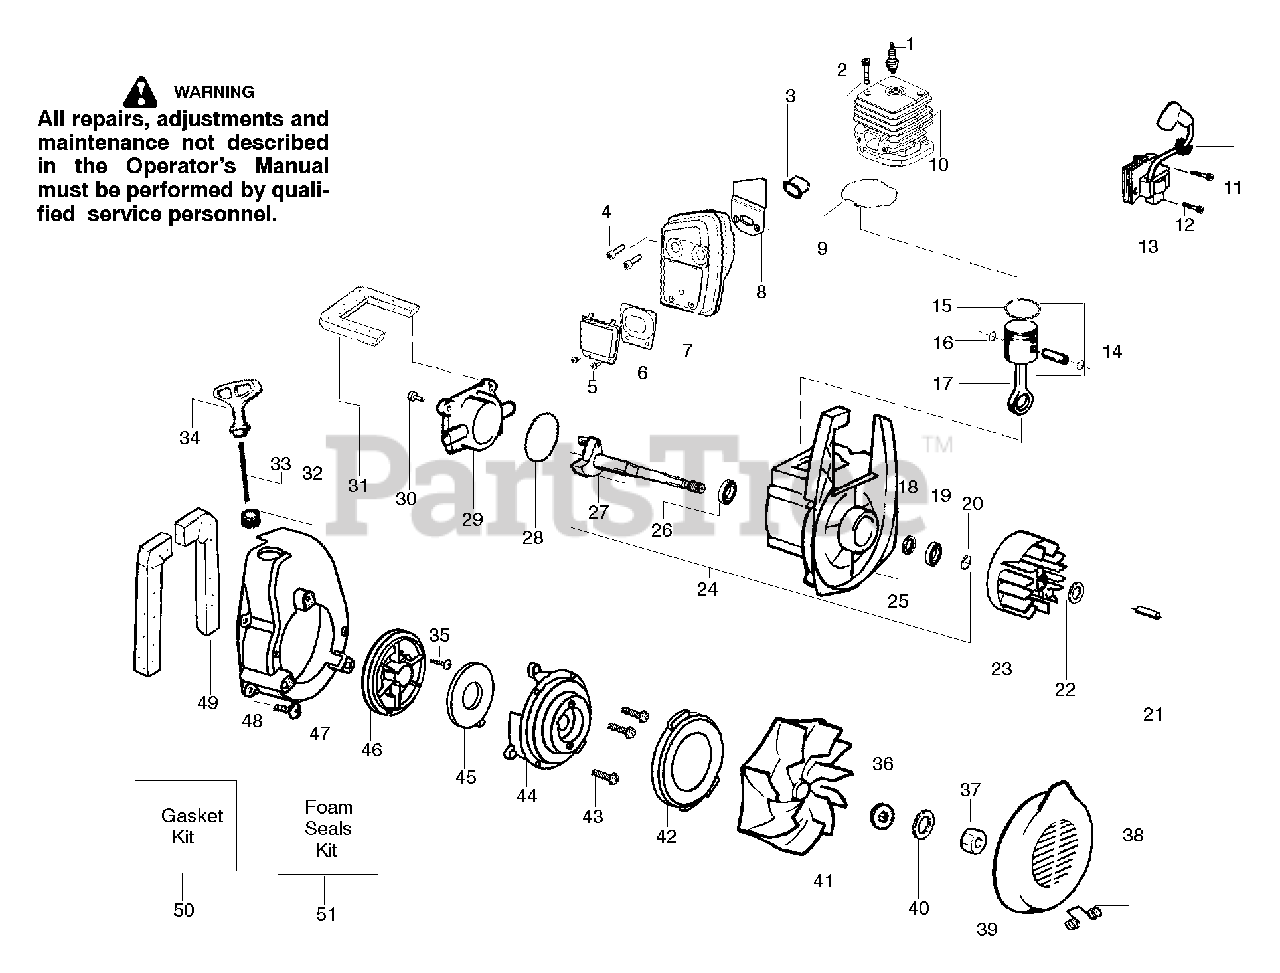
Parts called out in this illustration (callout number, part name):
1	Spark Plug (RCJ-6Y)
3	Insulator-Heat
4	Screw-Muffler-Internal
6	Kit-Spark Screen
7	Kit-Muffler
8	Gasket-Baffle (kit)
9	Gasket-Cylinder (kit)
10	Kit-Cylinder
11	Grommet-Ign. Module
12	Screw-Ignition Module
13	Ignition Module
14	Kit-Piston
15	Piston Ring
16	Retainer-Piston Pin
17	Assy-Connecting Rod
18	Kit-Crankcase Seal
19	Bearing-Outer
20	Retainer Ring-C'chaft
21	Spacer-Flywheel
23	Assy-Flywheel
24	Assy-Crankcase/Crank shaft
25	Assy-Crankcase
26	Bearing-Inner
27	Assy-Crankshaft
28	O-ring-C/case (kit)
29	Cover-Crankcase
30	Screw
31	Foam-219mm (kit)
32	Eyelet-Flange
33	Kit-Rope
34	Handle-Starter
35	Screw-Rope
36	Washer-Belleville
38	Spring-Return Cover
39	Inlet Door
40	Washer-Flat
41	Assy-Impeller
42	Seal-Ring
44	Housing-Pulley
45	Spring-Starter
46	Kit-Starter Pulley
47	Fan Housing
48	Screw
49	Foam-182mm (kit)
50	Kit-Gasket
51	Kit-Foam Seals
